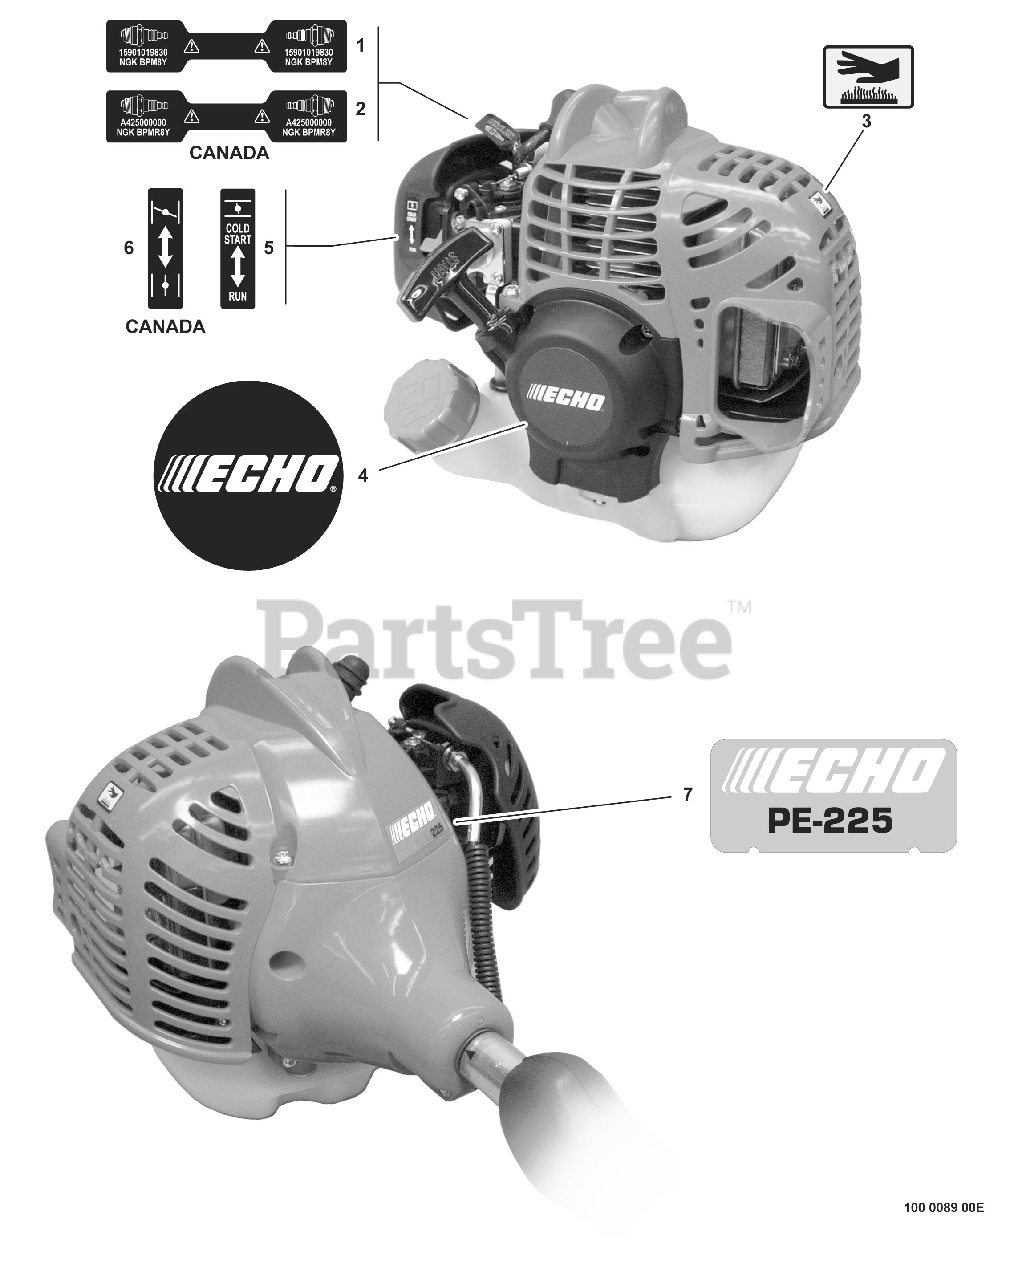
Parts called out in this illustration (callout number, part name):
1	LABEL - SPARK PLUG -- BPM-8Y
2	LABEL - SPARK PLUG -- BPMR-8Y
3	LABEL - HOT SURFACE
4	LABEL - ECHO
5	LABEL - CHOKE
6	LABEL - CHOKE
7	LABEL - MODEL PE-225
